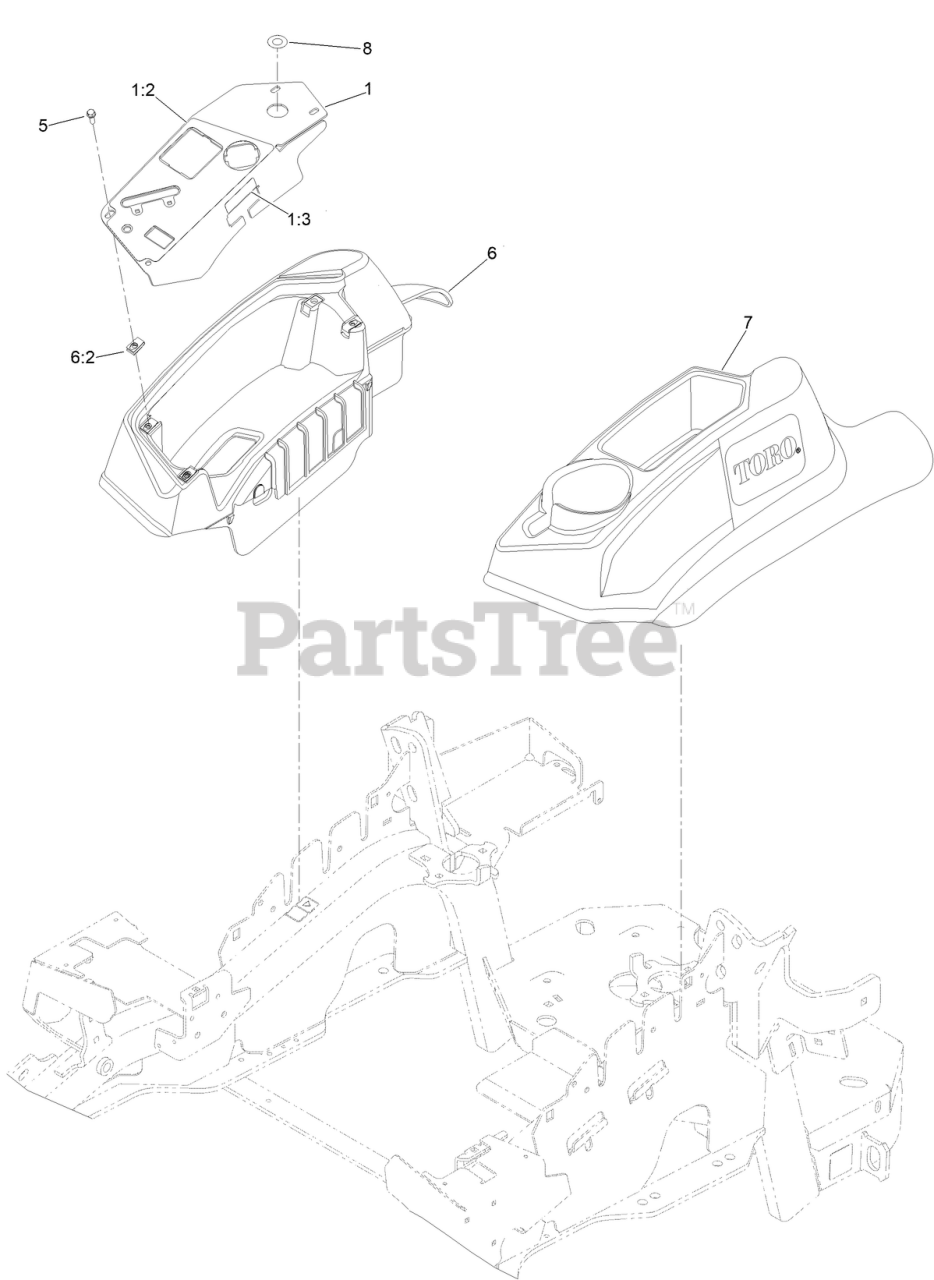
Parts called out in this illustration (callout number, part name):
1	CONTROL PANEL ASM
1:2	DECAL-PANEL, CONTROL
1:3	DECAL-FUSES
5	SCREW-HWH
6	RH CONSOLE ASM
7	CONSOLE-LH
8	DECAL-COVER 12V
